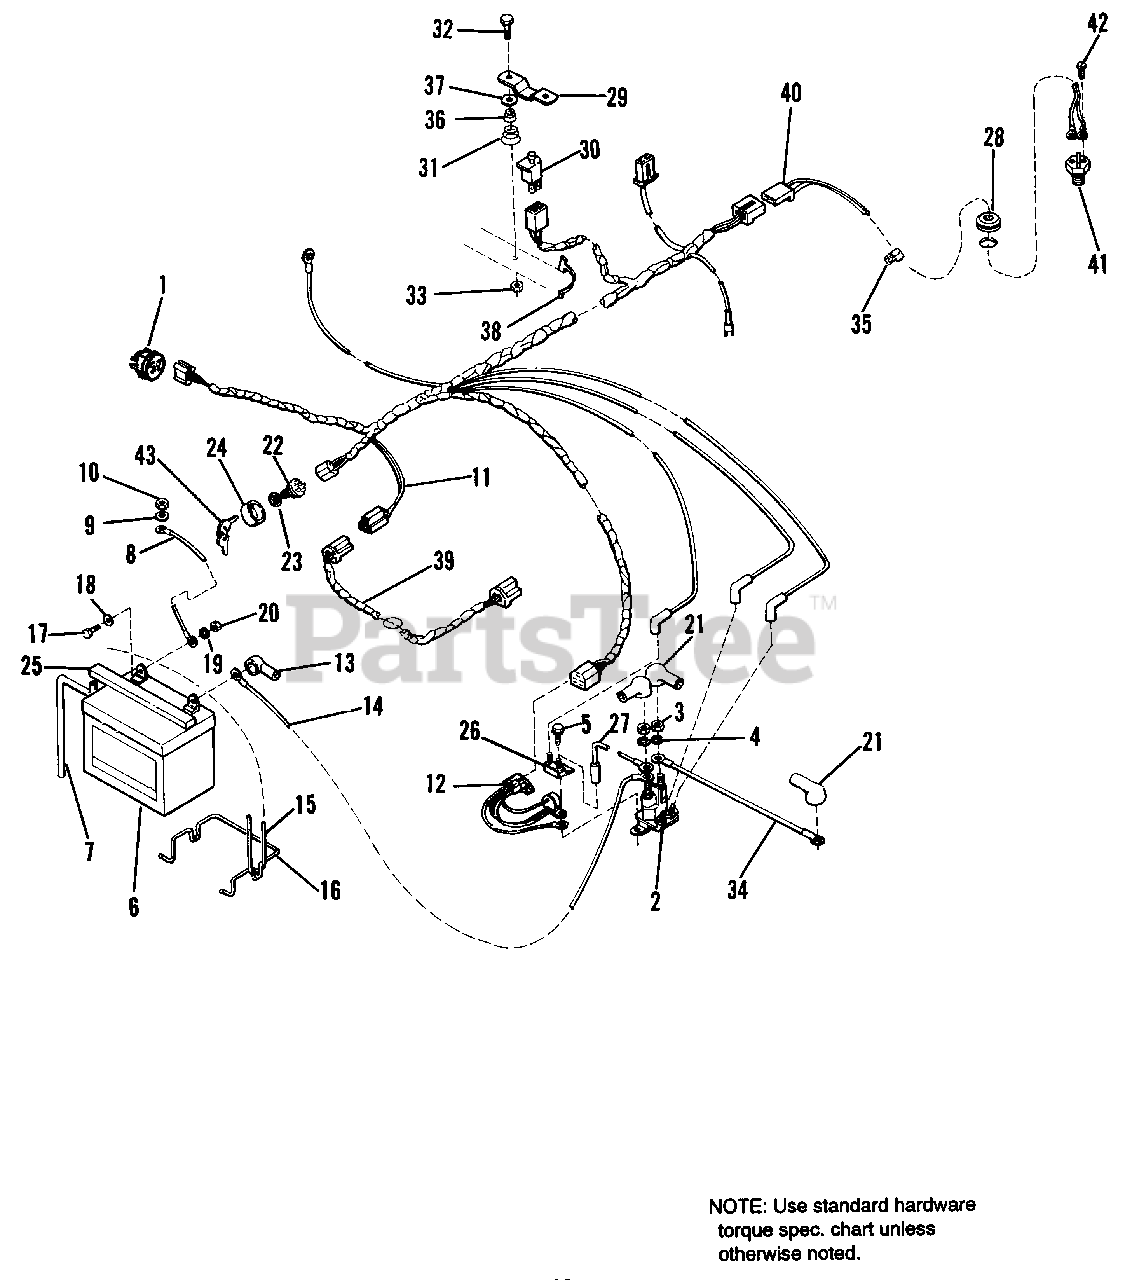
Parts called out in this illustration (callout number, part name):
1	SWITCH, PTO, Electric Clutch
2	SOLENOID
3	NUT, Hex, 5/16-15/64
4	LOCKWASHER, 5/16
5	SCREW, Hex, Flange, Taptite, 1/4-20 x 1/2
8	CABLE, Ground
8	WIRE ASSY., Neutral Switch (Hydro model)
9	LOCKWASHER, Ext. Tooth, 3/8
10	NUT, Hex, 3/8-16
11	WIRING HARNESS
12	MODULE, Interlock
13	BOOT, Insulator
14	CABLE, Battery-to-Solenoid
15	STRAP, Battery
16	BRACE, Battery
17	CAPSCREW, Hex Hd., 1/4-20 x 3/4
18	WASHER, Plain
19	LOCKWASHER, 1/4
20	NUT, Hex, 1/4-20
21	COVER, Terminal
22	SWITCH, Ignition
23	ADAPTOR, Nut
24	COVER, Key Switch
25	BATTERY CAP
26	CIRCUIT BREAKER
29	PLATE, Seat Actuator
30	SWITCH, Seat
32	CAPSCREW, Hex Hd., 5/16-18 x 1-3/4
33	NUT, Hex, Nylon Lock, 5/16-18
34	CABLE, Battery
35	CLAMP, Wire
37	WASHER, Flat, 13/32 x 7/8 x 5/64
38	CLIP
39	WIRE ASSY., PTO Clutch
40	WIRE ASSY., Neutral Switch (Gear model)
41	SWITCH, Neutral Start (Hydro only)
42	SCREW, Taptite, #10-20 x 5/8 (Hydro only)
